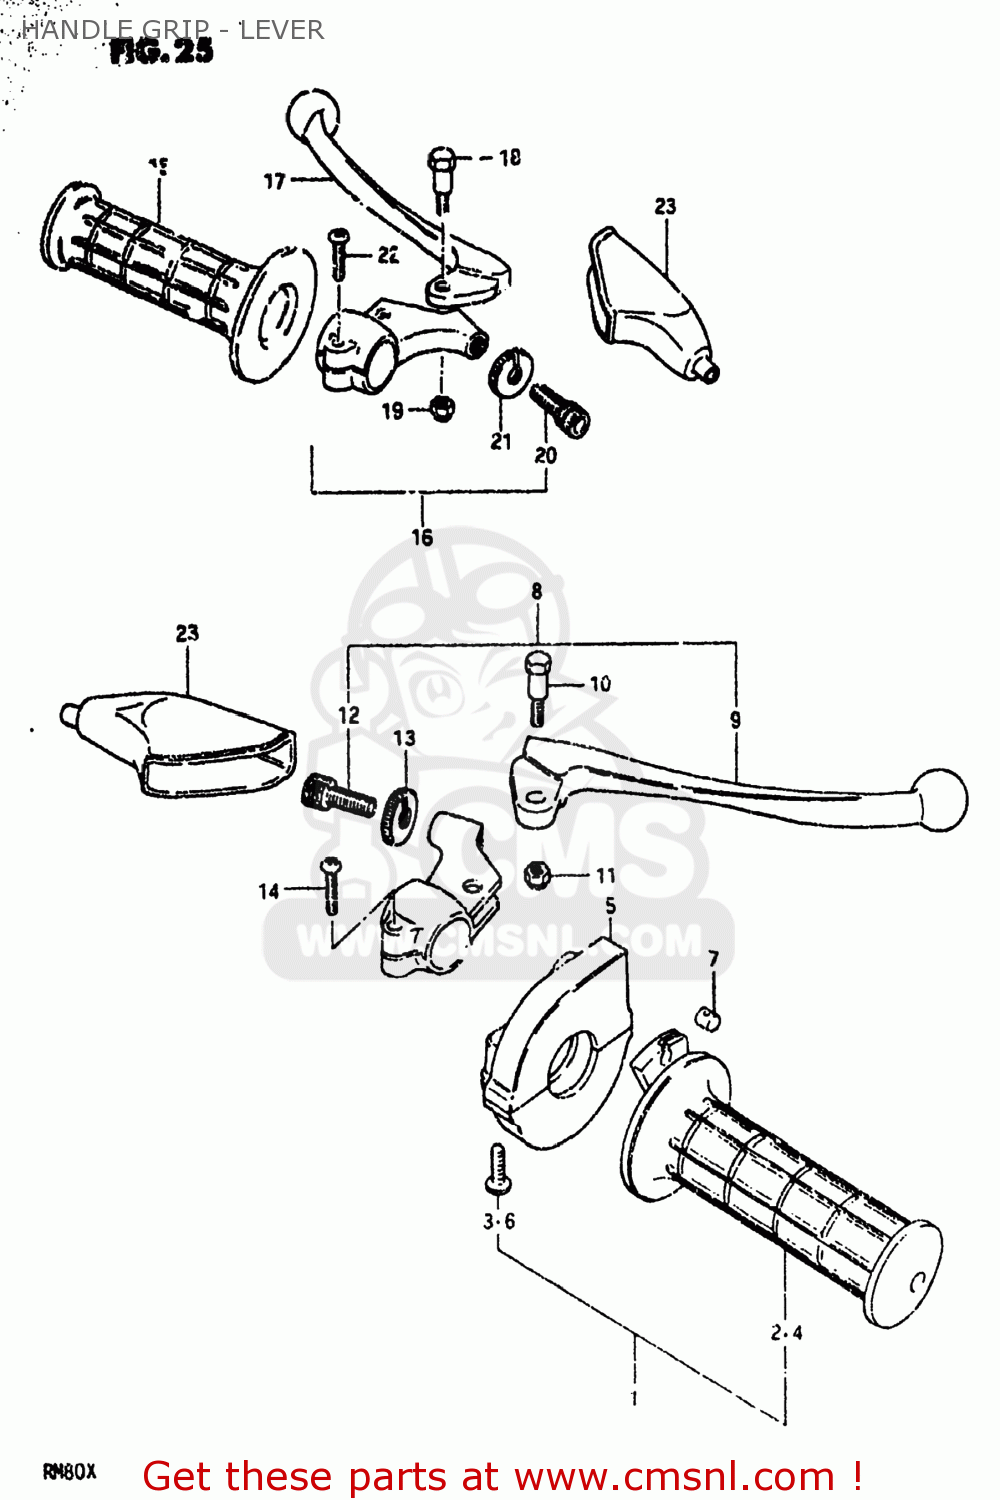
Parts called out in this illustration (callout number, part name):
1	CASE ASSEMBLY,THROTTLE
2	GRIP,THROTTLE
3	SCREW
4	GRIP,THROTTLE
5	CASE,THROTTLE
6	SCREW
7	PIECE,THROTTLE END
8	LEVER ASSEMBLY,BRAKE
9	LEVER,BRAKE
10	BOLT,LEVER
11	NUT 6MM
12	ADJUSTER,CABLE
13	NUT,CABLE ADJUSTER
14	SCREW
15	GRIP,LEFT
16	LEVER ASSY,CLUTCH
17	LEVER,CLUTCH
18	BOLT,LEVER
19	NUT 6MM
20	ADJUSTER,CABLE
21	NUT,CABLE ADJUSTER
22	SCREW
23	COVER,CLUTCH LEVER
